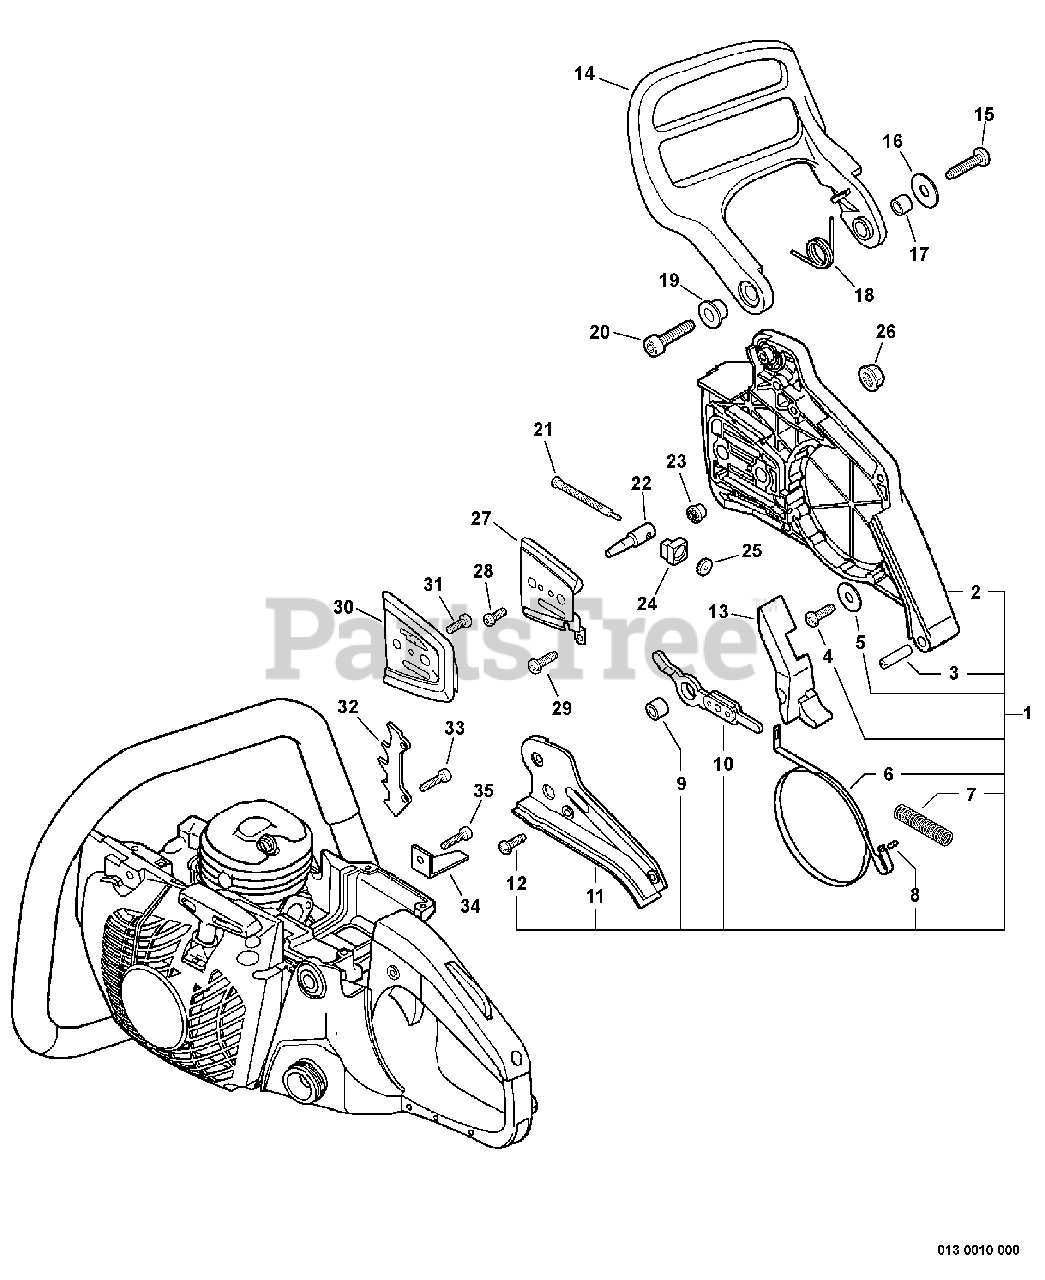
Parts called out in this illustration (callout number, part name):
1	CHAIN BRAKE ASSY - ORANGE
2	GUARD, SPROCKET
3	PIN - SPRING
4	SCREW - 4X16
6	BAND, BRAKE
8	PIN - 3X12
9	SPACER - 8
10	CONNECTOR, BRAKE
11	COVER, BRAKE
12	SCREW - 4X12 -- TAPPING
13	CUSHION
14	LEVER, BRAKE
15	SCREW - 4X14
17	SPACER - 8
19	COLLAR - 10
20	SCREW - 5X30
21	SCREW, TENSIONER
22	TENSIONER, CHAIN
23	GEAR - PINION
24	COLLAR - 8
25	GEAR - BEVEL
26	NUT - FLANGE
27	PLATE, GUIDE - OUTER
28	SCREW - 3X6
29	SCREW - 4X12 -- TAPPING
30	PLATE, GUIDE - INNER
31	SCREW - 4X6
33	SCREW - 5X12
34	CATCHER, CHAIN
35	SCREW - 5X14
